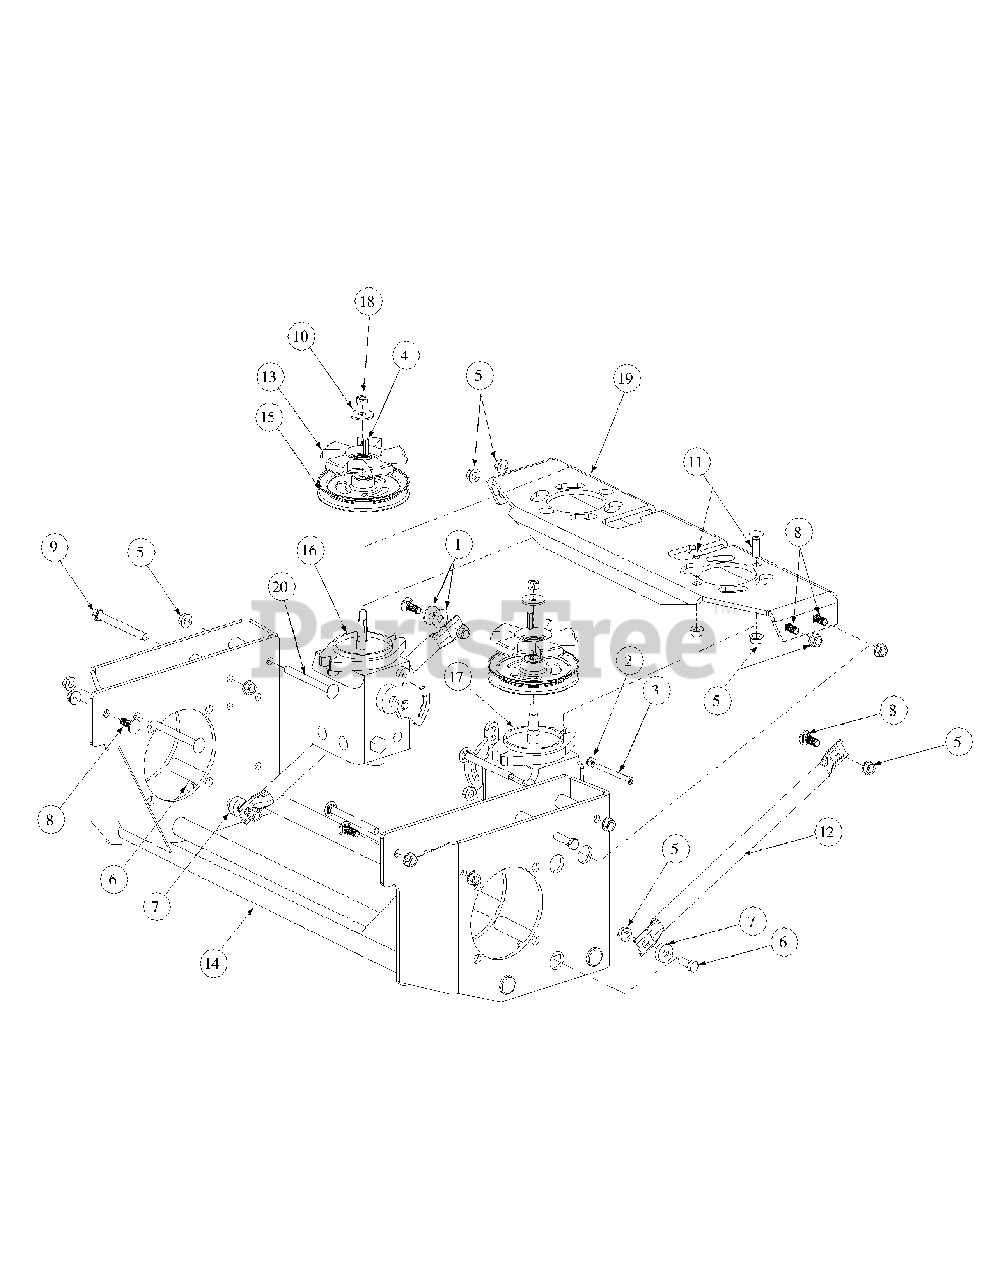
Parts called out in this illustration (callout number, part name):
1	Washer lock 3/8 zinc
2	Lock Nut, Nylon Insert, 1/4-20
3	Socket Head Cap Screw, 1/4-20 x 2-1/2
4	Key, 3/16" x 7/8"
5	Flange Lock Hex Nut, 3/8-16
6	Hex Cap Screw, 3/8 -16 x 1.25
7	Spacer, .406 ID x 1.00 OD x .38
8	Carriage Bolt, 3/8-16 x 1
9	Hex Cap Screw, 3/8-16 x 4.00
10	Flat Washer, .411 x 1.25 x .100
11	Carriage Screw, 3/8-16 x 1.25
13	Hydro Pulley Fan
14	Hydro Motor Frame Assembly
15	Hydro Pump Pulley
16	Hydro Pump, LH
17	Hydro Pump, RH
18	Hex Nut, 3/8-24
19	Hydro Pump Mount
20	Carriage Bolt, 3/8-16 x 4"
